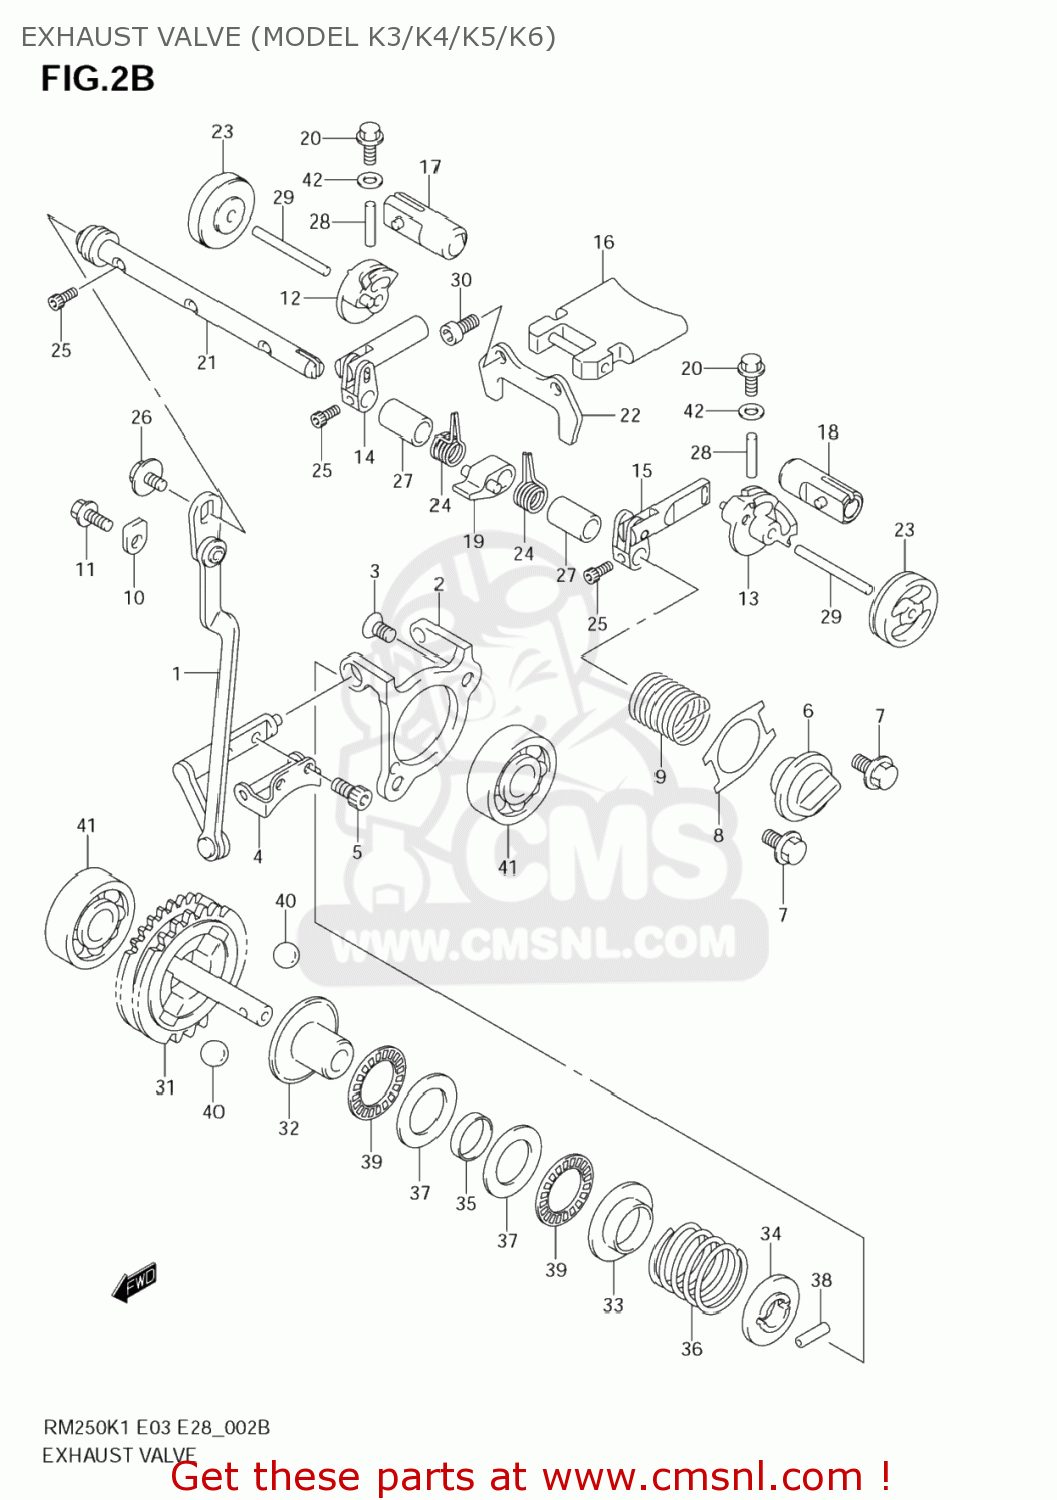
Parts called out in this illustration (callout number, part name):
1	ACTUATOR,EXHAUST VALVE
2	BASE,ACTUATOR
3	SCREW(5X10)
4	ARM,ACTUATOR
5	BOLT(4X8)
6	CAP,EXHAUST VALVE SHAFT SPRING
7	BOLT(5X10)
8	GASKET,EXHAUST VLV SPRING CAP (NAS)
9	SPRING,CYL COVER NO.2 SHAFT
10	RETAINER
11	BOLT(6X10)
12	CAM,EXHAUST SIDE VALVE,R
13	CAM,EXHAUST SIDE VALVE,L
14	ROD ASSY,EXH SIDE VALVE CAM,R
15	ROD ASSY,EXH SIDE VALVE CAM,L
16	VALVE ASSY,EXHAUST MAIN
17	VALVE ASSY,EXHAUST SIDE,R
18	VALVE ASSY,EXHAUST SIDE,L
19	ARM ASSY,EXH MAIN VALVE
20	CAP,EXHAUST SIDE VLV STOP PIN
21	SHAFT,EXHAUST VALVE
22	PLATE,EXHAUST MAIN VALVE
23	SPACER,EXHAUST SIDE VALVE
24	SPRING,EXHAUST MAIN VALVE ARM
25	BOLT(4X8)
26	BOLT(5X12)
27	SPACER(8.5X12X19)
28	ROLLER(4X23.8)
29	PIN(4X39.8)
30	BOLT
31	GOVERNOR,DRIVE
32	GOVERNOR,DRIVEN
33	STOPPER,GOVERNOR SPRING NO.1
34	STOPPER,GOVERNOR SPRING NO.2
35	SPACER,GOVERNOR
36	SPRING,GOVERNOR
37	SHIM(15X28X1)
38	ROLLER(3X12.5)
39	BEARING(15X28X2)
40	BALL
41	BEARING(8X22X7)
42	GASKET(8.2X14X1).6 (NAS)
